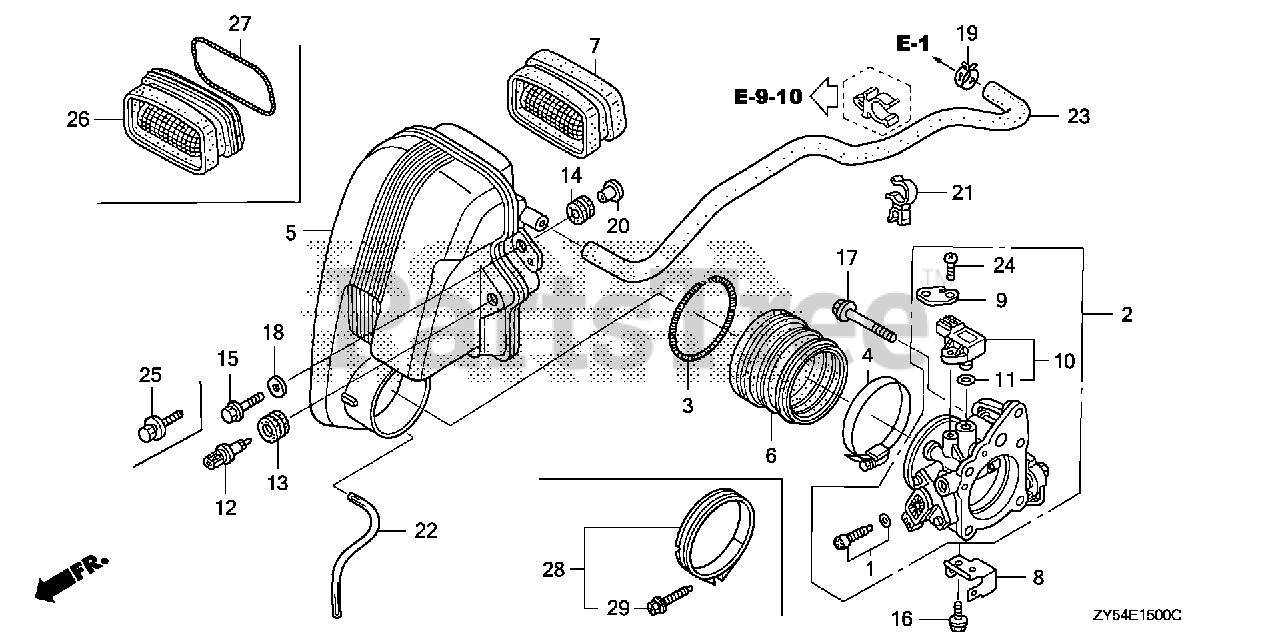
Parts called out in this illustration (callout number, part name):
2	BODY ASSY., THROTTLE
3	SPRING, AIR FLOW TUBE
4	BAND, AIR FLOW
5	CASE, MUFFLER
6	GROMMET, MUFFLER
7	GROMMET, MUFFLER DUCT
8	BRACKET E, HARNESS CLIP
9	BRACKET, SENSOR WIRE
10	SENSOR ASSY., MAP
12	SENSOR ASSY., AIR TEMPERATURE (MATSUSHITA DENSHI)
13	GROMMET, TA SENSOR
14	GROMMET, CASE (LOWER)
15	BOLT, FLANGE (6X25)
16	BOLT, FLANGE (6X12)
17	BOLT, FLANGE (8X60)
18	WASHER, PLAIN (6MM)
19	CLAMP, TUBE (D17)
20	COLLAR, MODULE IGNITION CONTROL CASE (CDI)
21	CLAMP, FUEL HOSE
22	BULK HOSE, VINYL (4X7X8000) (4X7X160)
23	BULK HOSE, VACUUM (12X1000) (12X740)
24	SCREW, PAN (5X18)
25	BOLT-WASHER (6X25)
26	GROMMET, MUFFLER DUCT
27	SPRING, MUFFLER DUCT GROMMET
